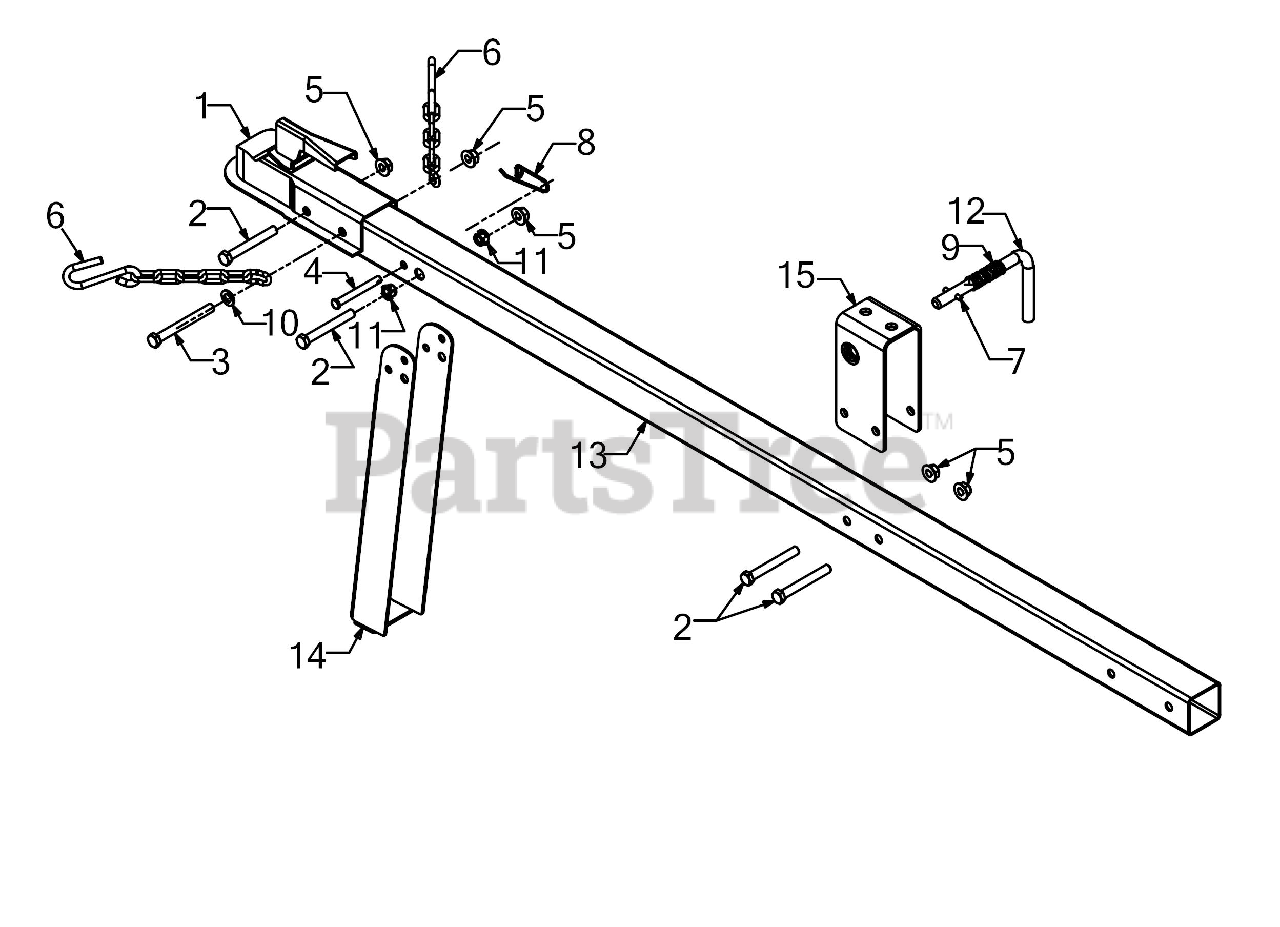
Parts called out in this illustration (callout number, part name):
1	HITCH COUPLING ASSEMBLY
2	SCREW 3/8-16 x 3 GR8
3	SCREW 3/8-16 x 3.50 GR5
4	CLEVIS PIN 5/16 x 2.5
6	LOGSPLITTER TOW CHAIN
7	SPRING PIN 3/16 x 1.00
8	SPRING PIN
9	COMPRESSION SPRING
10	FLAT WASHER
11	BUSHING .380 ID
12	LATCH ROD
